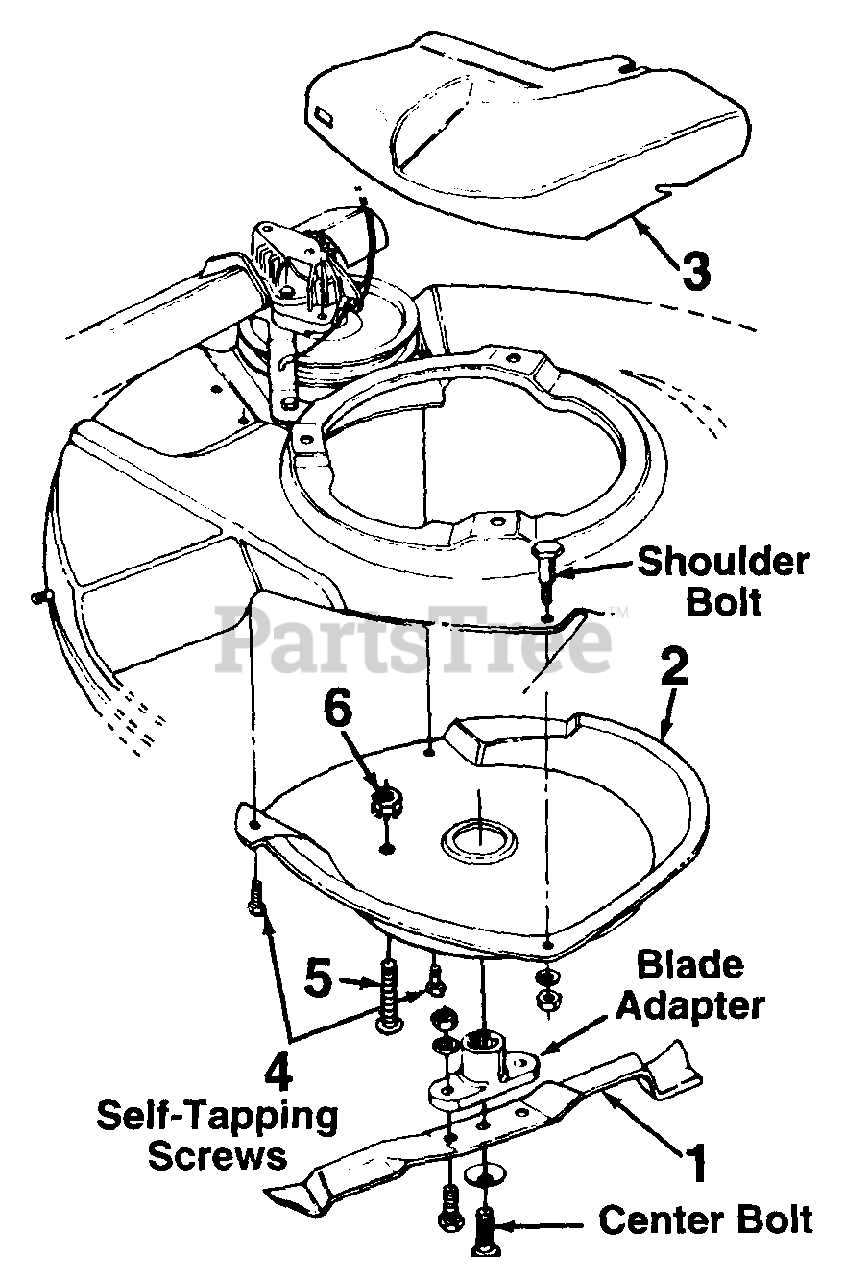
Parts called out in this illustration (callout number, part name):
1	Mulching Blade
4	Self-Tapping Screw
5	Phillips Scr. 1/4-20 x 1.5" Lg.
6	Hex Sems Nut 1/4-20 Thd.
